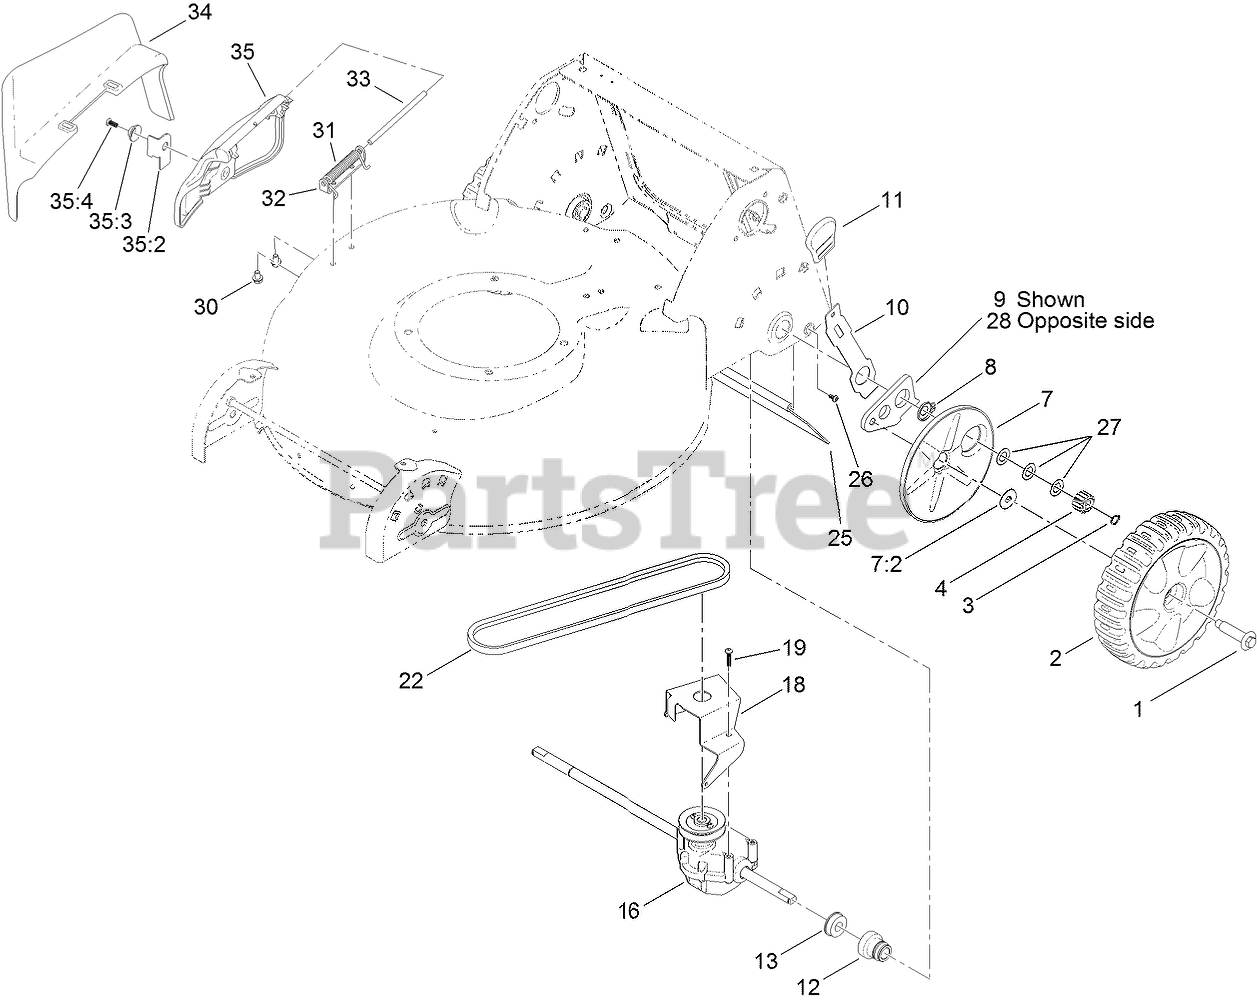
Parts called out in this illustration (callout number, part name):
1	BOLT-SHOULDER
2	8 INCH WHEEL AND GEAR ASM
3	RING-RETAINING
4	GEAR-PINION, 15T
7	WHEEL COVER ASM
7:2	WASHER-STEPPED
8	RING-RETAINING
9	ARM-REAR PIVOT, LH
10	ARM-SPRING, REAR
11	KNOB-HOC
12	RETAINER-BEARING, HOC
13	BEARING-BALL
16	TRANSMISSION ASM
18	BRACKET-TRANSMISSION
19	SCREW-PLASTITE
22	V-BELT
25	SHIELD-TRAILING
26	SCREW-PTH
27	WASHER-PLAIN
28	ARM-REAR PIVOT, RH
30	SCREW-HWH
31	SPRING-TORSION
32	BRACKET-COVER
33	ROD-COVER
34	CHUTE-DISCHARGE, SIDE
35	DISCHARGE DOOR ASM
35:2	LATCH-DOOR
35:3	CAP-DOOR
35:4	SCREW-PLASTITE
